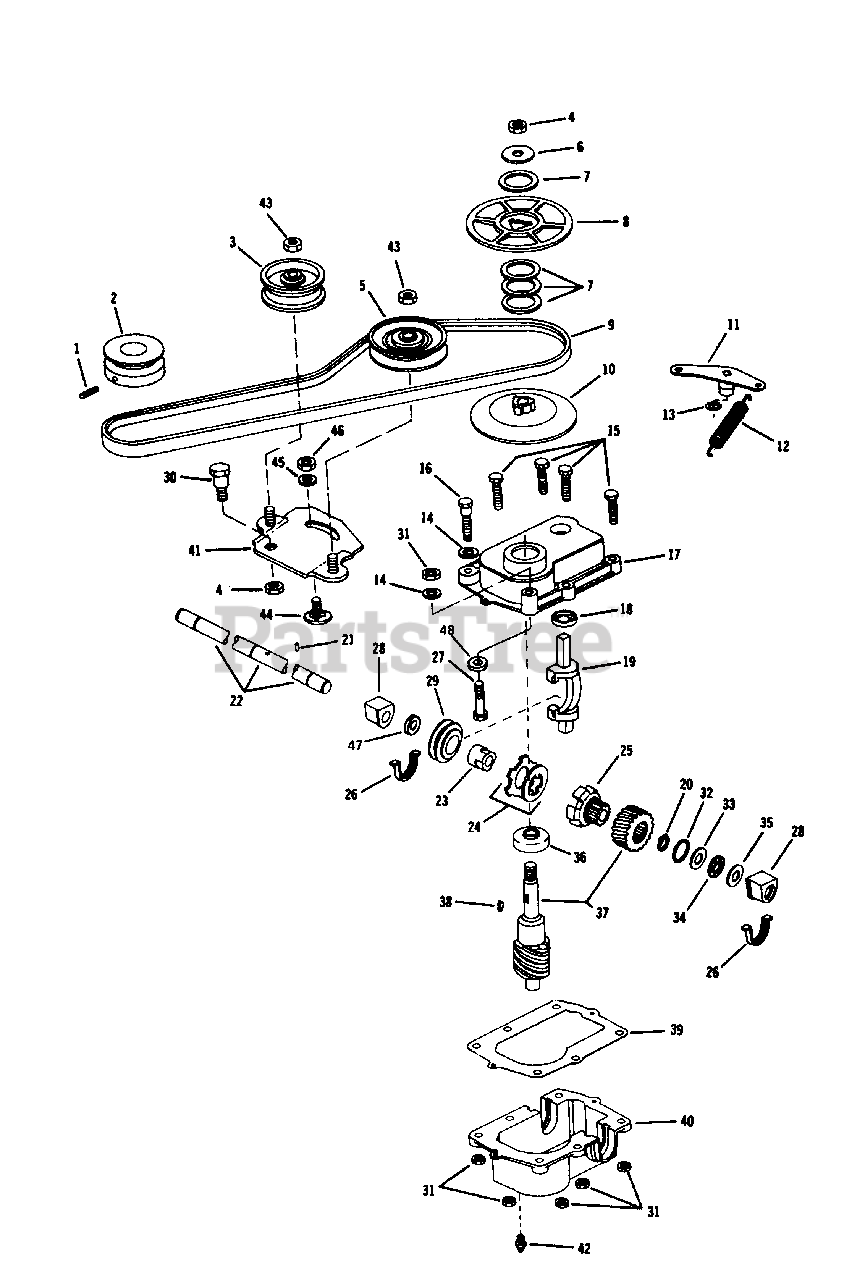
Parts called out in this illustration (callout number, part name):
1	Set Screw
2	Pulley-Engine
3	Pulley-Idler Variable Speed
4	Nut
5	Idler-V-Belt
6	Washer
7	Washer
8	Pulley Half-Upper
9	V-Belt
10	Pulley Half-Lower
11	Shift Arm
12	Spring-Extension
13	O-Ring
14	Washer
15	Screw-Hex Head Cap
16	Bolt-Shoulder
17	Gear Case-Upper
18	Seal Guide
19	Fork-Shift
20	Ring-Retaining
21	Pin
22	Drive Shaft
23	Driven Sleeve
24	Disc Clutch Kit
25	Driver
26	Packing
27	Screw
28	Bearing and Seal Asy.-Gearcase
29	Collar
30	Bolt-Shoulder
31	Nut
32	Washer-Thrust
33	Washer-Thrust
34	Bearing-Thrust
35	Washer-Thrust
36	Bearing
37	Worm Wheel and Shaft Assembly
38	Key
39	Gasket
40	Gear Case-Lower
41	Idler Plate
42	Lubrication Fitting
43	Nut-Thin
44	Bolt-Square Neck
45	Washer
46	Nut
47	Washer
48	Lockwasher
